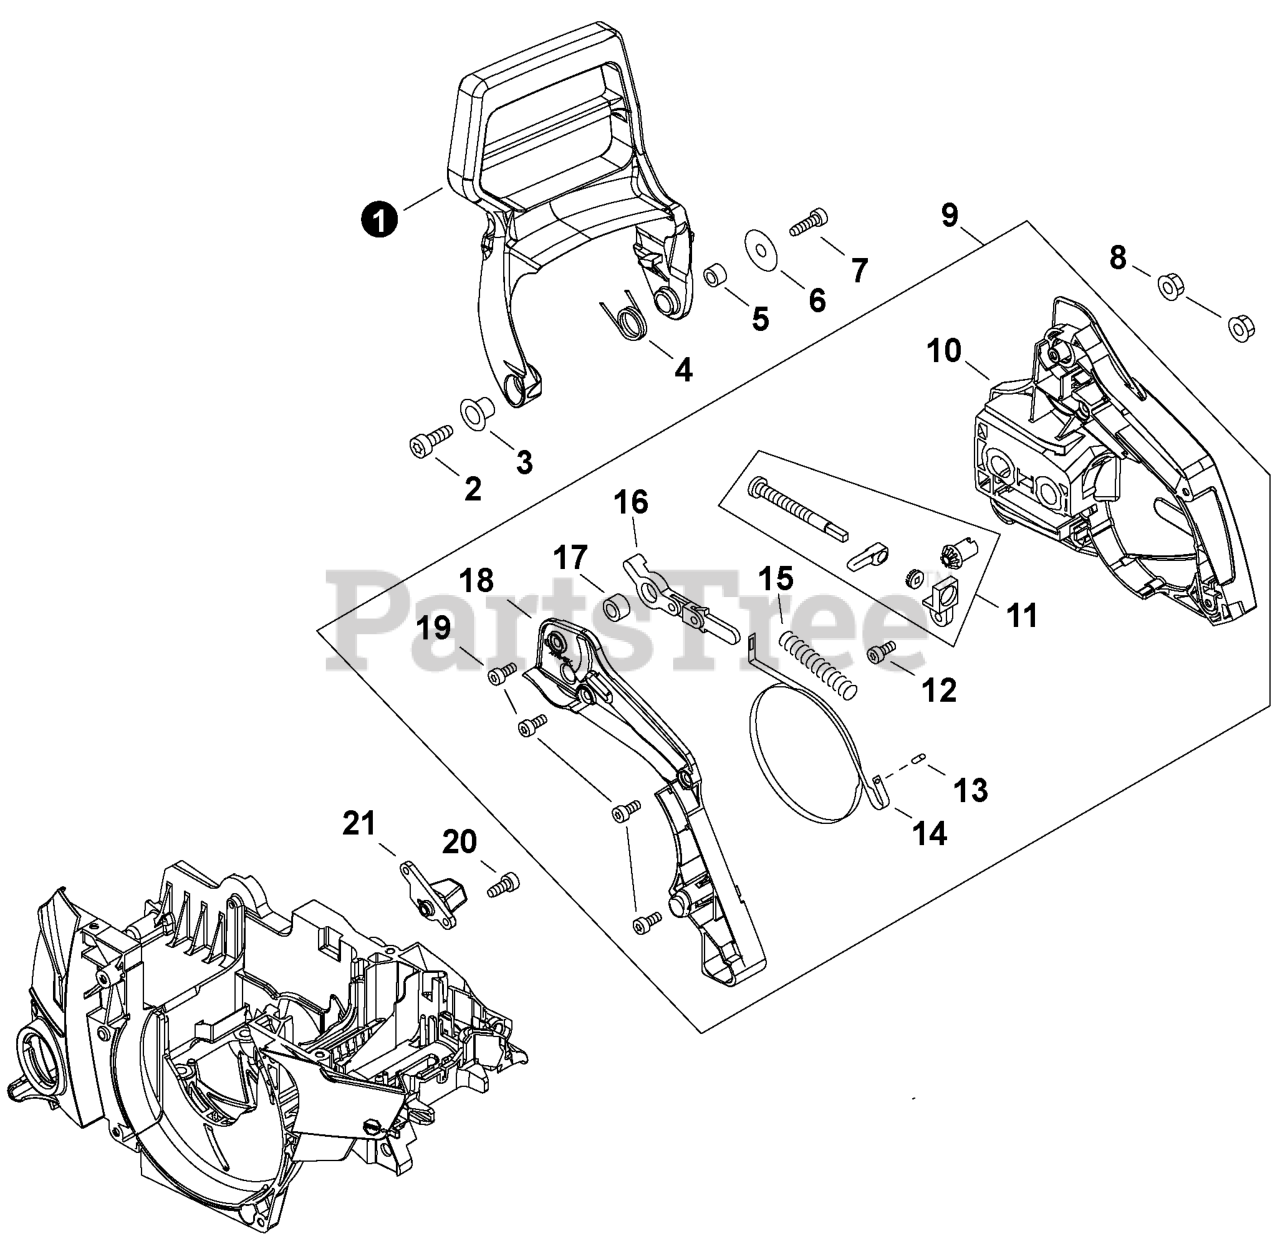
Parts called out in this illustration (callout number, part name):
1	LEVER, BRAKE
2	BOLT, TORX 5x20
3	COLLAR 10
4	SPRING, TORSION
5	SPACER 8x12x9
6	WASHER 4.2x16.5x1
7	BOLT, TORX 4x16
8	NUT, FLANGE M8x1.25
9	BRAKE ASSY, CHAIN
10	GUARD, SPROCKET
11	TENSIONER KIT, CHAIN
12	BOLT, TORX 4x16
13	PIN 3x12
14	BAND, BRAKE
15	SPRING, COMPRESSION
16	CONNECTOR, BRAKE
17	SPACER 8x12x9
18	COVER, BRAKE
19	BOLT, TORX 4x16
20	BOLT, TORX 5x20
21	CATCHER, CHAIN
